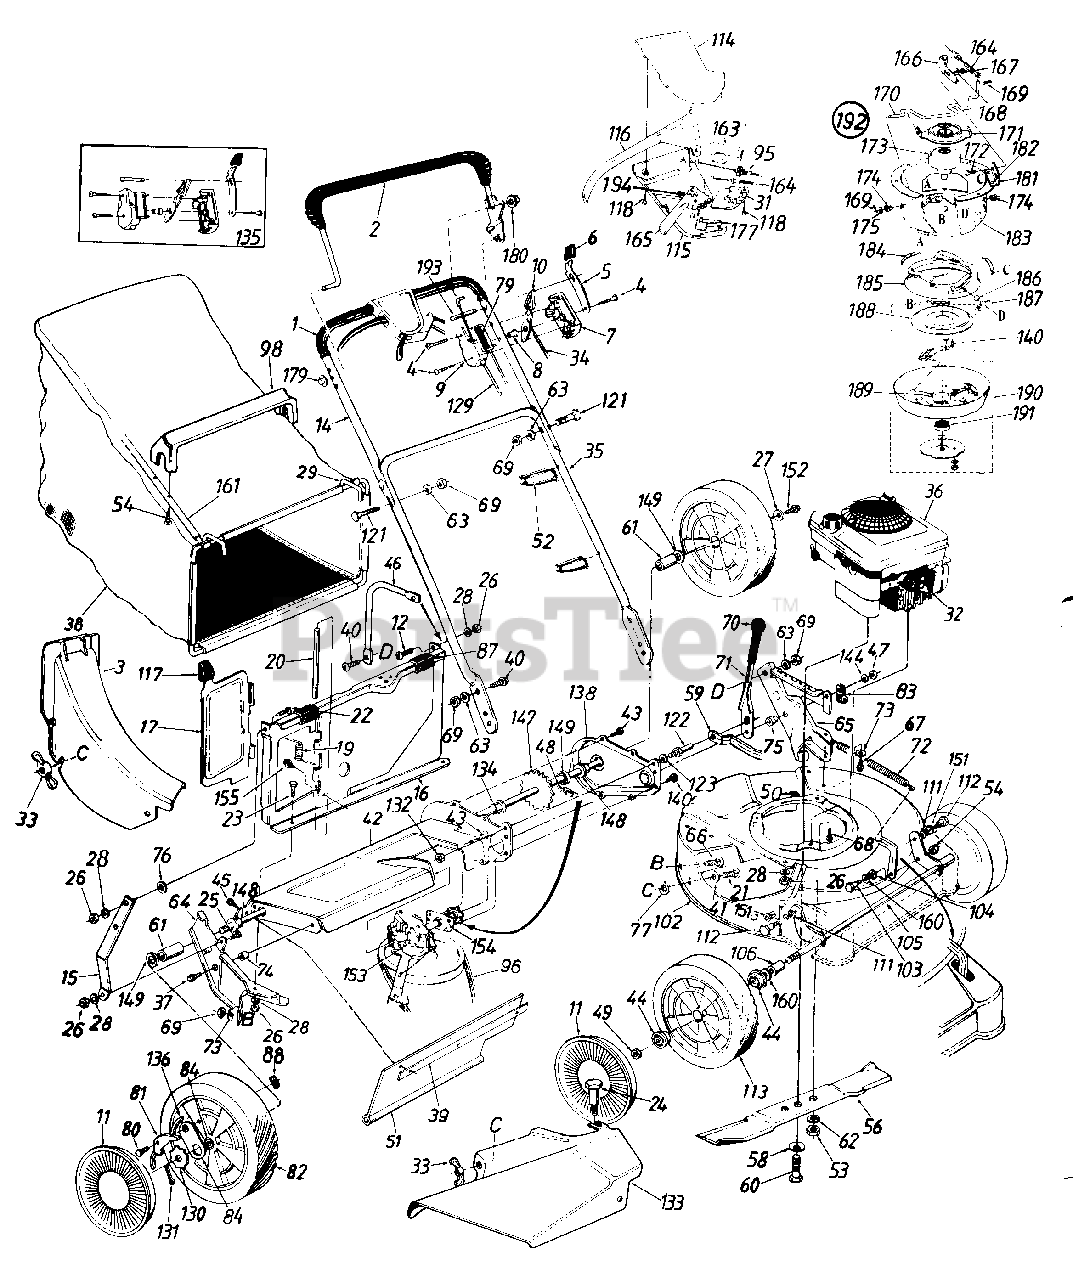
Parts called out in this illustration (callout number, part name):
1	Foam Grip
2	Control Handle Ass'y.-L.H.
3	Rear Discharge Chute Ass'y.
4	Truss Mach. Scr. #12 x 1.50" Lg.
5	Lockout Spring
6	Grip
7	Control Panel Half
8	Control Disc Pin
9	Clutch Panel Half
10	Throttle Control Lever
11	Hub Cap
12	Truss Mach. Scr. 1/4-20 x .62" Lg.
14	Upper Handle-Painted
19	Torsion Spring
20	Pivot Pin
21	Carriage Bolt 1/4-20 x .62"
22	Truss Mach. Scr. 1/4-20 x 3/4" Lg
23	Hex Bolt 1/4-20 x .50" Lg.
24	Shoulder Bolt .312 Dia. x .18 Lg.-Special
25	Hex Bolt 1/4-20 x .62" Lg.
26	Hex Nut 1/4-20 Thd.*
27	Bell-Wash. 1/4" I.D.
28	L-Wash. 1/4" I.D.
31	S.P. Control Cover
32	Spark Plug Insulator
33	Wing Nut w/Washer
34	Throttle Control Wire 61"
35	Lower Handle-Painted
36	Engine
38	Grass Bag (Black)
39	Retaining Strip
40	Truss Mach. Scr. 5/16-18 x .75" Lg.
41	Fl-Wash. .344" I.D. x .62"
44	Flange Ball Bearing 1/2" I.D.
45	Hex AB-Tap Scr. 1/4 x .62"
46	Catcher Panel Support Arm
47	Hex Patch L-Nut 3/8-24 Thd.
48	#48 Chain .500" Pitch x 30 Links
49	Hex L-Nut 1/2-20 Thd.
51	Rear Flap 3.75" x 17.30" Lg.
52	Cable Tie
53	Hex Nut 3/8-24 Thd. (Grade 8)
54	Hex AB Scr. #12 x 1.25" Lg.
56	21" Blade
58	Bell-Wash. .46" I.D.
59	Height Adj. Connecting Arm
60	Hex Bolt 7/16-20 x 2.0" Lg. (Grade 5)
61	Spacer .513" I.D. x .703" O.D. x .69" Lg.
62	L-Wash. 3/8" I.D.*
63	L-Wash. 5/16" I.D.
64	R.H. Handle Wheel Brkt. Ass'y.
65	L.H. Handle Wheel Brkt. Ass'y.
66	Carriage Bolt 5/16-18 x .62"
67	Hex Wash. Hd. B-Tap Scr. 5/1 6-1 8
68	Hex Wash. Hd. TT-Tap Scr. 3/8-1 6
69	Hex Nut 5/16-18 Thd.
71	Height Adj. Lever
72	Extension Spring .75'1 O.D. x8" Lg.
73	Bell-Wash. 5/16 I.D.
74	Spacer
75	Shld. Spacer .500" Dia.
76	Fl-Wash. .285" I.D. x 1.25"
77	Bolt Retainer 1/4 x .50" O.D.
79	Control Label
80	Shld. Scr. .342" Dia. x .268
81	Pawl
82	Wheel Ass'y. Comp. (Silver)
83	Clamp
84	Bearing 1/2" I.D.
87	Panel Clip
88	Flat Weld Nut 1/4-20 Thd.
95	S.P. Cable
96	"V"-Belt
98	Bag Handle
102	21" Deck Ass'y.
103	Shld. Bolt .5" Dia. x .295
104	Bell-Wash. .515" I.D. x 1.0" O.D.
105	Front Axle Ass'y.
106	Sleeve .526" I.D. x .690" O.D. x .880" Lg.
111	Intern. L-Wash. 3/8 I.D.
112	Shld. Bolt .575" Dia. x .42
113	Wheel Ass'y. Comp. (Silver)
114	Self-Propelled Control Cover
115	Self-Propelled Control Cover
116	Control Lever
117	Door Grip
118	Fl-"C"-Sunk Hd. Tap Scr. #10 x .75" Lg.
121	Curved Carr. Bolt 5/16-18 x 1.38" Lg.
122	Shld. Pin 3/8-24 x 1.43" Lg.
123	L-Wash. 3/8" I.D.*
129	Control Cable 49" Lg.
130	Ratchet Wheel 1.62" O.D.
131	Cotter Pin 1/8" Dia. x 1.00" Lg.*
132	Hex Jam Nut 3/8-24 Thd.
133	Side Chute Deflector Ass'y.
134	Hex Flange Bearing
135	Kit-Control Housing Comp.
136	Spring-Nylon
144	Fl-Wash. .385" I.D. x .87"
147	Rear Shaft Ass'y. 21.94" Lg.
148	Hex Flange Bearing .506" I.D. Plastic
149	Fl-Wash. .531" I.D. x .930"
151	Flanged Nyliner Brg.
152	Hex Bolt 1/4-20 x .62" Lg. (Grade 5)
153	Transmission Comp.
155	Hex B-Tap Scr. #10 x .38
160	Fl-Wash. .51" I.D. x .75" O.D.
163	6-Speed Rack Cable Brkt.
164	Spd. Control Cable-50" Lg.
165	6-Spd. Shift Lever
168	Bell-Wash. .265" I.D. x .75" O.D.
169	Cot-Pin 3/32" Dia. x .75" Lg.
170	Shift Rod
171	Movable Pulley Half Ass'y.
172	Carr. Bolt 1/4-20 x .50" Lg.
173	Fixed Pulley Adapter
174	Flanged Bushing
175	Fl-Wash. .328" I.D. x .68" O.D.
177	Shift Lever Spring
179	Push Cap
180	Push Cap
181	6-Speed Cable Mtg. Brkt.
182	Rivet .252" Dia. x .31"
183	Clutch Housing
184	Ext. Spring 1.75" Lg.
185	Brake Cup Cone
186	Steel Ball .5" Dia.
187	Ball Block
188	Clutch Cone
189	Comp. Spring 2.0" Lg.
190	Clutch Blade Housing Ass'y.
191	Ball Brg. .669" I.D. x 1.574"
192	Blade Brake Clutch Ass'y. Comp.
193	Lock Pin
194	3 Tooth Rack Gear Insert
